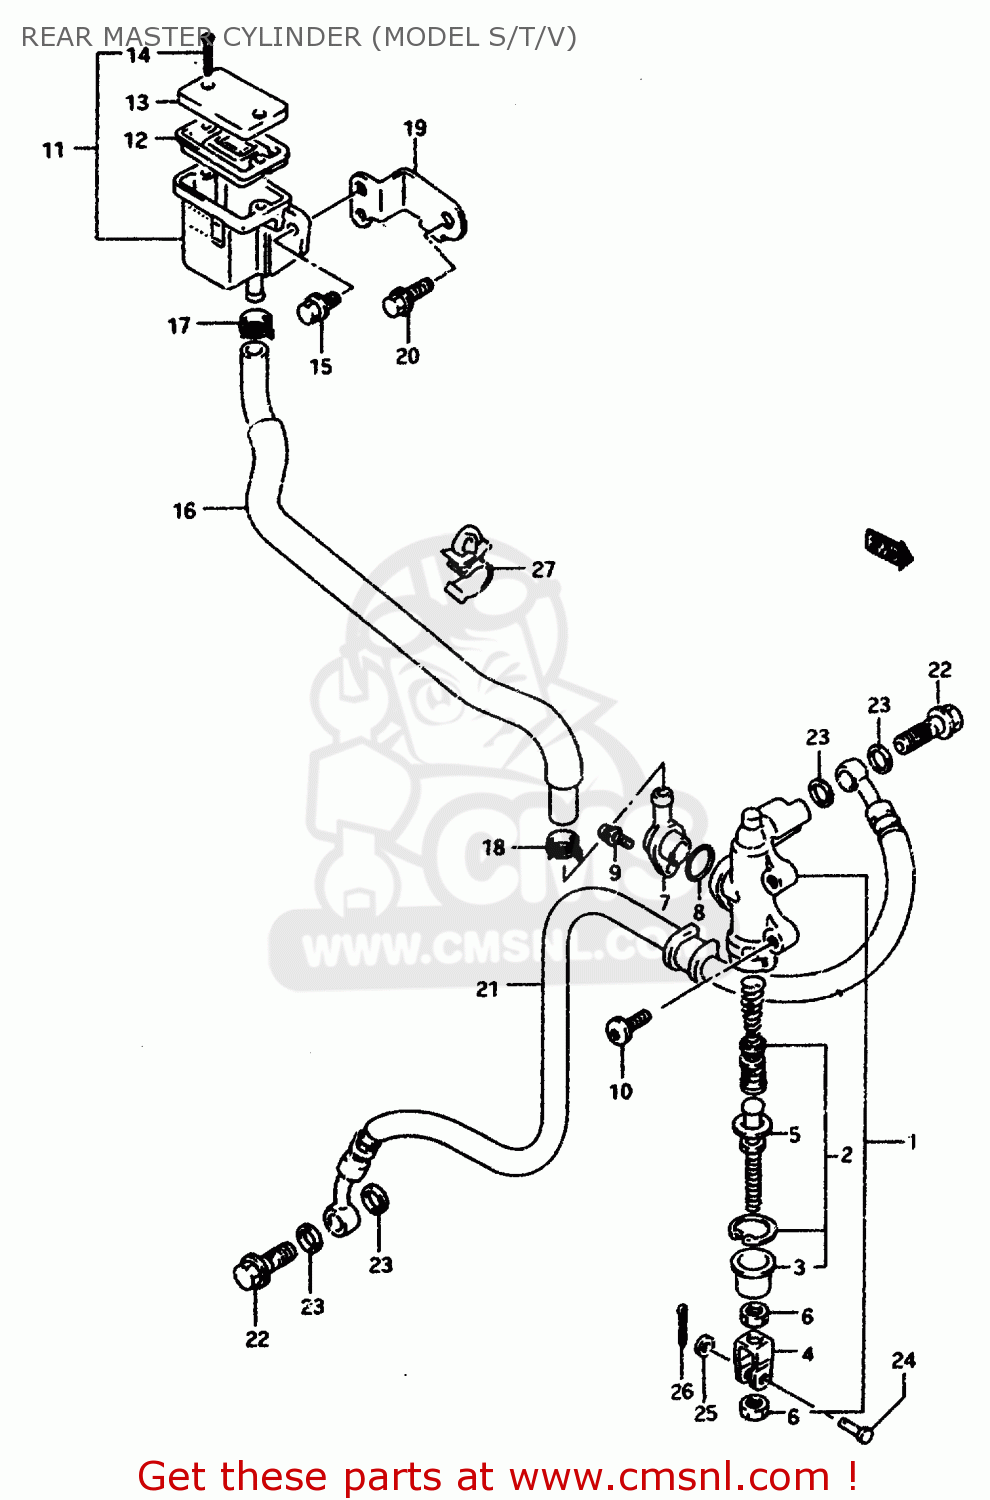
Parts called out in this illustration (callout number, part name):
1	CYLINDER ASSEMBLY,REAR MASTER
2	PISTON/CUP SET
3	BOOT
4	YOKE
5	ROD,PUSH
6	NUT
7	CONNECTOR
8	O RING
9	SCREW
10	BOLT 8X20
11	TANK ASSY,RESERVOIR
12	DIAPHRAGM
13	CAP
14	SCREW
15	BOLT
16	HOSE,RESERVOIR TANK
17	CLIP
18	CLIP
19	PLATE,RESERVOIR TANK
20	BOLT
21	HOSE,RR BRAKE
22	BOLT UNION
23	WASHER(10X15X1.5)
24	PIN
25	WASHER
26	PIN
27	CLAMP
28	LOCK WASHER
